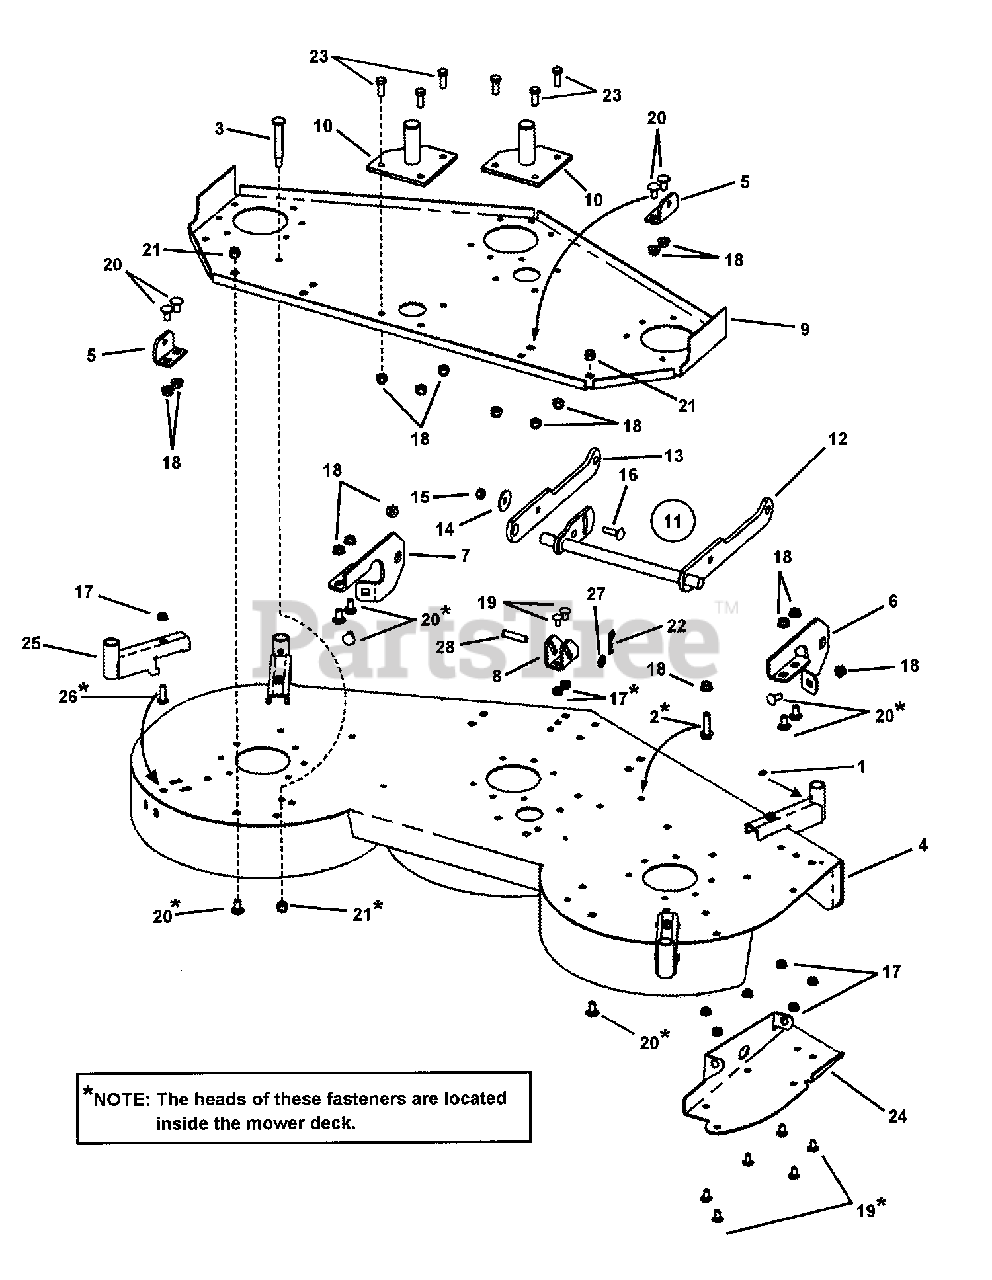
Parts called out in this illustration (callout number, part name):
1	LUBE FITTING, Straight (press-fit for .187 dia. Hole)
2	BOLT, 3/8-16 x 1-1/2" Hex Flange Lock, GR5
3	SHOULDER BOLT, 3/8-16 thread
4	WELDMENT, 48" Deck
5	BRACKET, Rear Lift- 48" Deck
6	BRACKET, Front Hanger- Right Hand
7	BRACKET, Front Hanger Left Hand
8	BRACKET, Front Hanger- 48" Deck
9	STIFFNER, 48" Deck- LT
10	WELDMENT, Idler Plate
11	ASSEMBLY, Front Lift Arm (Includes items 12 thru 16)
12	WELDMENT, Front Lift Arm
13	ARM, Lift
14	WASHER, Cone, 13/32 x 1-13/32" Diameter
15	NUT, 3/8-16 Hex
16	BOLT, 3/8-16 x 1-1/4" Square Neck Carriage, GR5
17	NUT, 5/16-18 Hex Flange Lock, GR5
18	NUT, 3/8-16 Hex Flange Lock
19	BOLT, 5/16-18 x 5/8" Short Neck Carriage, GR5
20	BOLT, 3/8-16 x 3/4" Short Neck Carriage, GR2
21	NUT, 3/8-16-3B Hex Nyloc
22	HAIR PIN, 3/32 x 1.5"
23	SCREW, 3/8-16 x 1" Hex Head Cap, GR5
24	BRACKET, Hinge (48" Deck)
25	WELDMENT, Caster
26	BOLT, 5/16-18 x 1-1/8" Short Neck Carriage, GR5
27	WASHER, 3/8" Flat SAE
28	PIN, 3/8 x 1-5/8" Clevis
